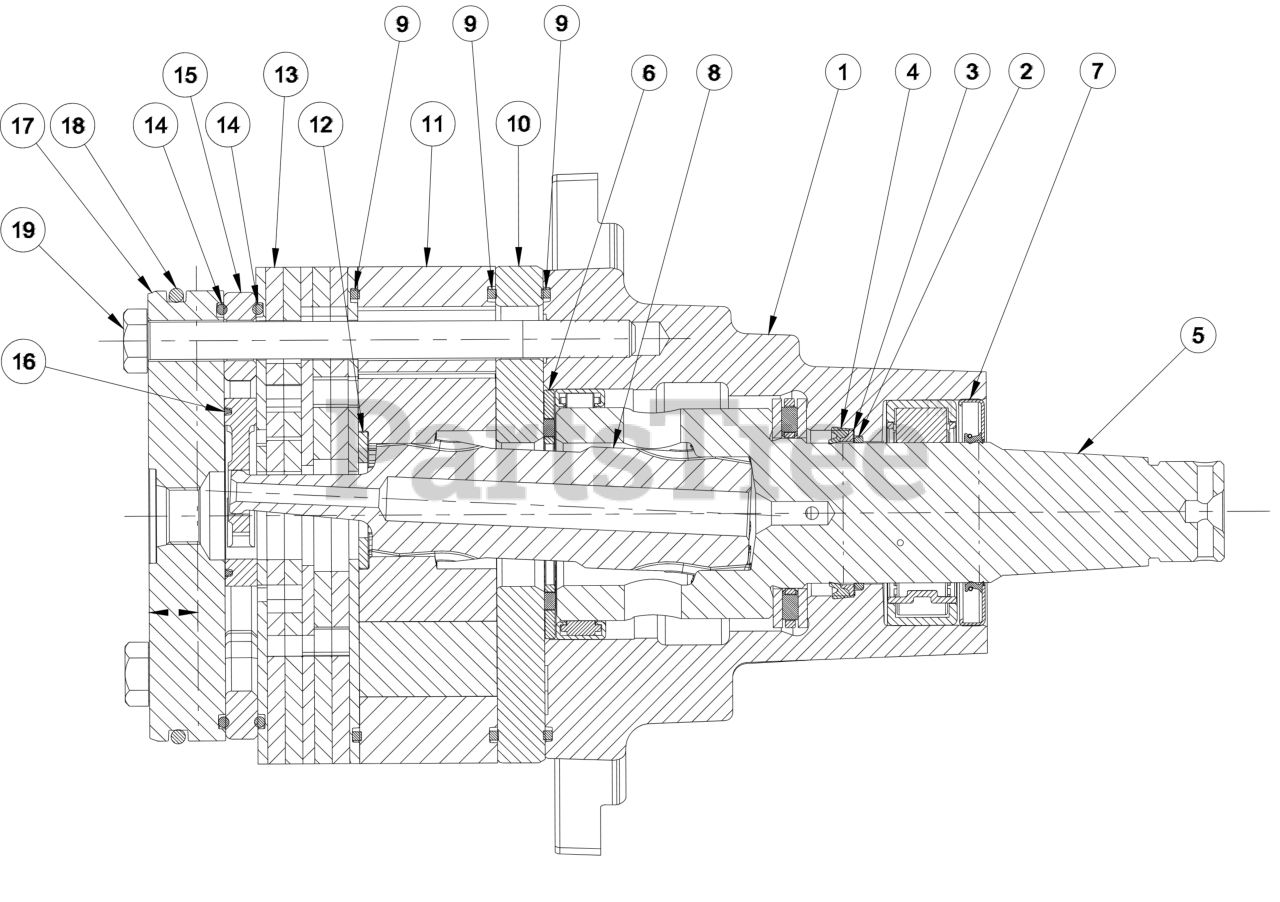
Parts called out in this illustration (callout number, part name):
1	Not Serviceable/ Order Complete Assembly
2	BACK-UP RING
3	BACK-UP WASHER
4	SHAFT SEAL
5	COUPLING SHAFT
6	THRUST BEARING
7	DIRT & WATER SEAL
8	Not Serviceable/ Order Complete Assembly
9	SEAL RING (FLUOROCARBON)
10	WEAR PLATE
11	Not Serviceable/ Order Complete Assembly
12	THRUSH WASHER
13	Not Serviceable/ Order Complete Assembly
16	COMMUTATOR SEAL
17	Not Serviceable/ Order Complete Assembly
